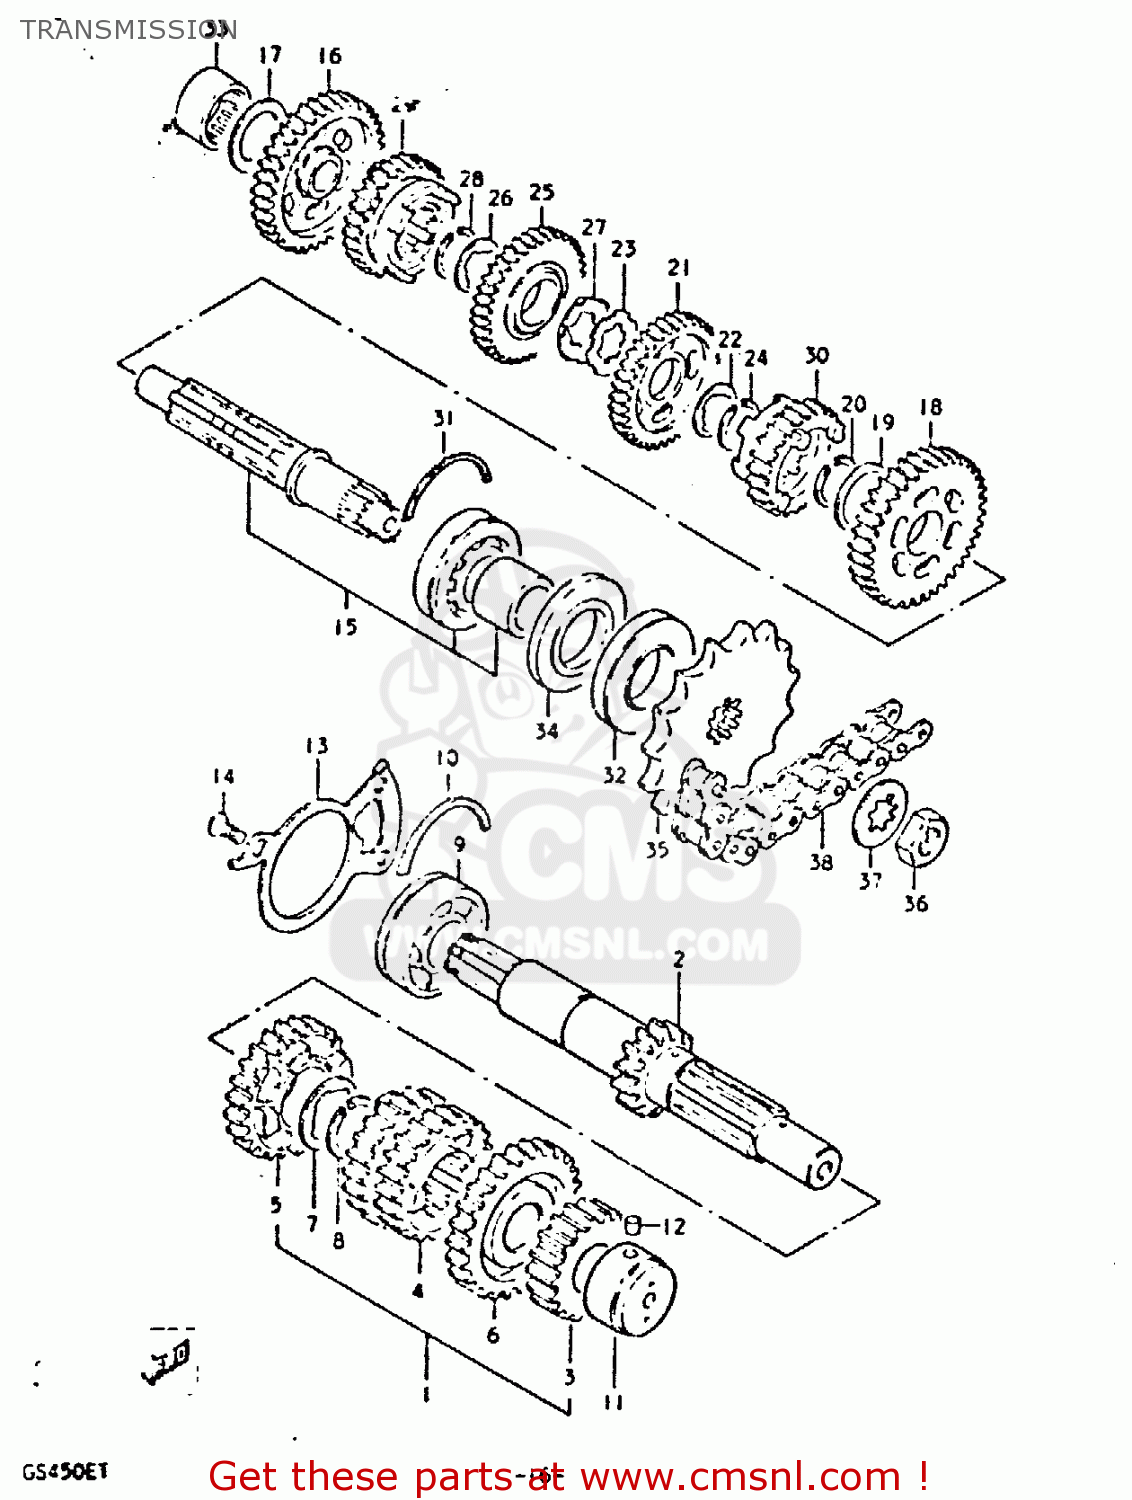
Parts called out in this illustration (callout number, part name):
1	SHAFT,COUNTER
2	SHAFT,COUNTER
3	GEAR,2ND DRIVE(NT:18)
4	GEAR,THIRD DRIVE
5	GEAR,FIFTH DRIVE
6	GEAR,SIXTH DRIVE
7	WASHER
8	CIRCLIP
9	BEARING(25X62X17)
10	C-RING
11	ROLLER BEARING (20X34X2
12	PIN
13	PLATE,COUNTERSHAFT BEARING
14	SCREW
15	SHAFT,DRIVE
16	GEAR,FIRST DRIVEN
17	WASHER
18	GEAR,SECOND DRIVEN
19	WASHER
20	CIRCLIP
21	GEAR,THIRD DRIVEN
22	WASHER,LOCK
23	WASHER,LOCK
24	CIRCLIP
25	GEAR,FOURTH DRIVEN
26	WASHER,LOCK
27	WASHER
28	CIRCLIP
29	GEAR,5TH DRIVEN(NT:25)
30	GEAR,SIXTH DRIVEN
31	C-RING
32	SEAL,OIL(32X62X7)
33	ROLLER BEARING (20X34X1
34	SEAL,OIL(32X62X5.5)
35	SPROCKET,ENGINE(NT:16)
36	NUT
37	WASHER
38	CHAIN ASSEMBLY,DRIVE
